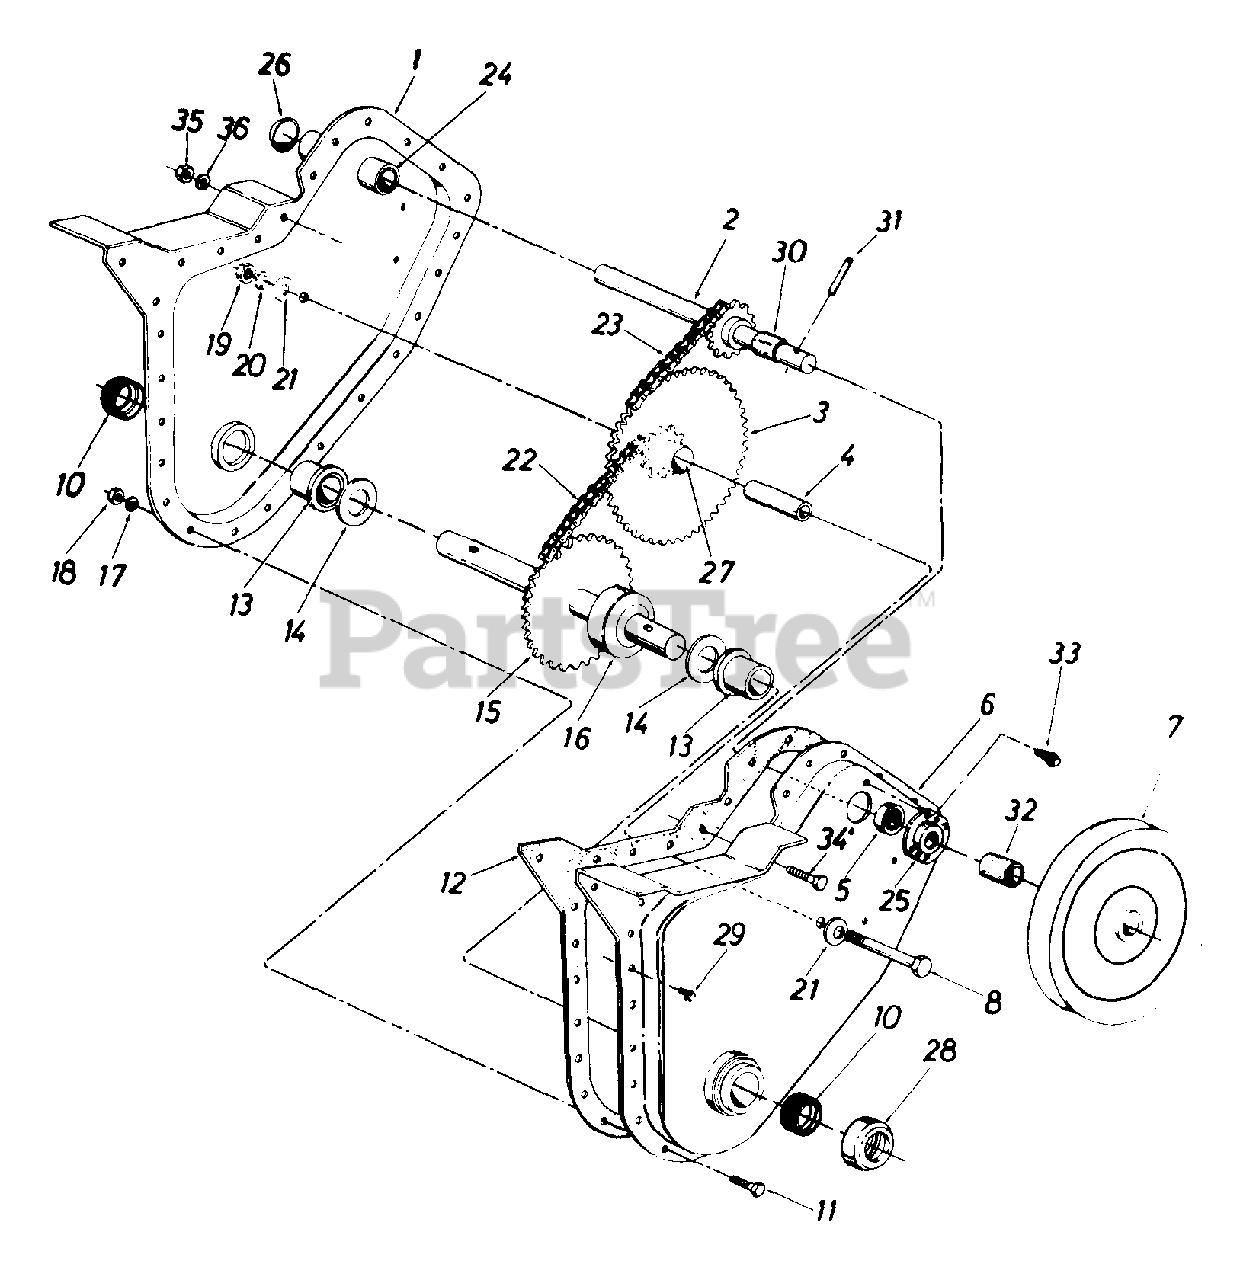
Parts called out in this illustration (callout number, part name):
1	Chain Case Ass'y.- R.H.
2	Input Shaft Ass'y.
3	Hub and Sprocket Ass'y.
4	Bearing Inner Race
5	Ball Bearing
6	Chain Case Ass'y.- L.H.
7	Pulley - Chain Case
8	Hex Bolt 3/8-24 x 2.5" Lg.
11	Hex Bolt 1/4-28 x .625" Lg.
12	Gasket
13	Flange Brg. .879" I.D.
14	Fl-Wash. .88" I.D. x 1.5"
15	Tine Shaft Ass'y.
16	Spacer 7/8" I.D. x 2" O.D. x .68" Lg.
17	L-Wash. 1/4" I.D.
18	Hex Nut 1/4-28 Thd.
19	Hex Ins. L-Nut 3/8-24 Thd.
20	L-Wash. 3/8" I.D.
21	Bell-Wash. .406" I.D.
22	Chain #420 1/2" Pitch x 37 Links
23	Chain #35 .375" Pitch x 49 Links
24	Bearing .62" I.D x .813"
25	Bearing Housing
26	Expansion Plug 13/16" Dia.
27	Bearing
28	Dust Cap
29	Hex Wash. Hd. Self-Tap Scr. 1/4-20 x .50" Lg.
30	Spacer .63" I.D. x .77" O.D. x .38" Lg.
31	Spring Pin Spiral 1/4" Dia. x 1 1/2" Lg.
32	Spacer .647 x 1.25"
33	Hex Wash. Hd. Self-Tap Scr. 1/4-20 x .38" Lg.
34	Hex Bolt 5/16-18 x .75" Lg.
35	Hex Nut 5/16-18 Thd.
36	L-Wash. 5/16" I.D.
